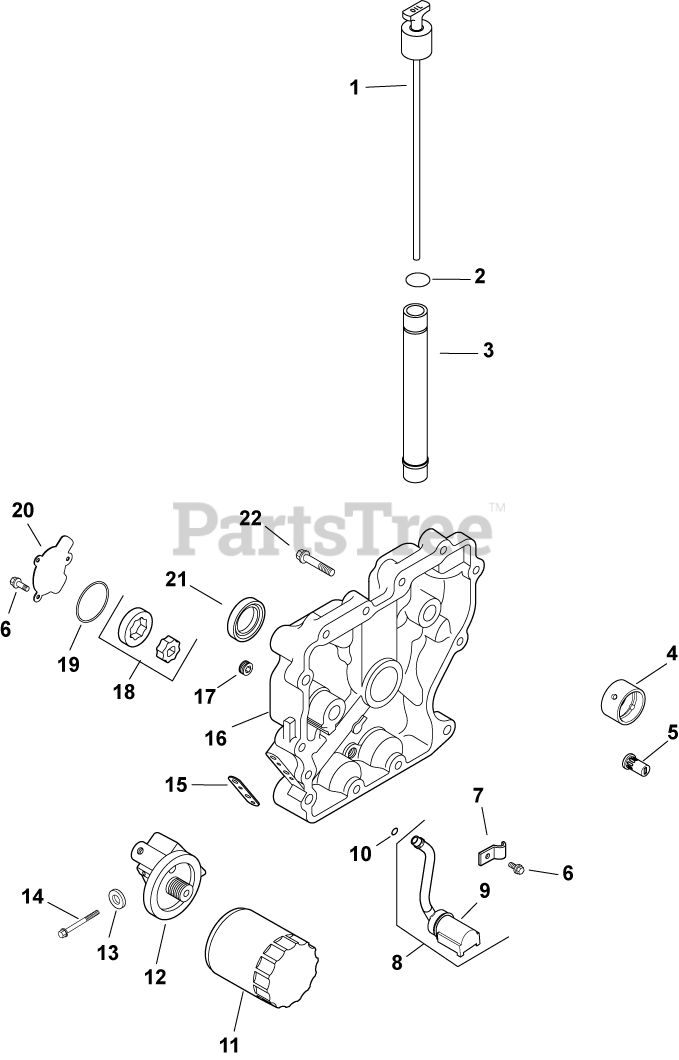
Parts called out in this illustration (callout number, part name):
3	KIT, OIL FILL TUBE - METAL
4	BEARING, CRANKSHAFT
5	VALVE, OIL PRESSURE RELIEF
6	SCREW,FLG THD FRM M5X0.8X16-(#25086398S)
8	KIT, OIL PICK-UP
9	PICK-UP, OIL SCREEN
10	O-RING (.5" DIA)
11	OIL FILTER
12	ADAPTER - DISCONTINUED
14	SCREW, FLG M6X1.0X60
15	GASKET, OIL FILTER ADAPTER
16	CLOSURE PLATE ASSEMBLY - DISCONTINUED
17	PLUG, CTSK PIPE 1/8"
18	PUMP ASSEMBLY, OIL
19	O-RING (1.78" DIA)
20	COVER, OIL PUMP
21	SEAL, OIL
22	SCREW, FLG M8X1.25X45
